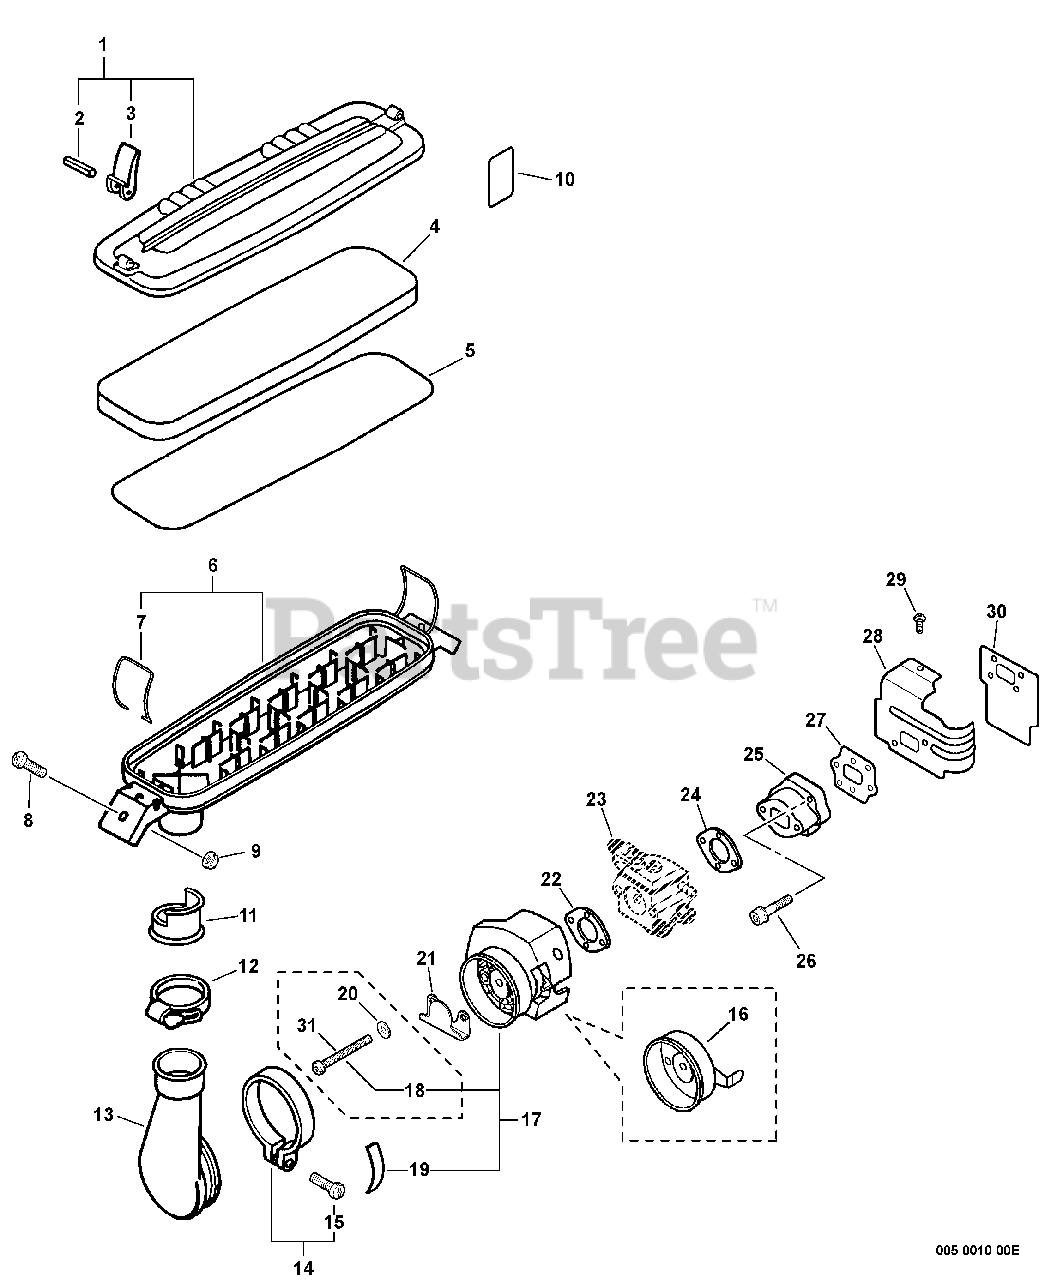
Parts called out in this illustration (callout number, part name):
1	COVER, AIR FILTER
2	PIN, SPRING 3×25
4	FILTER, AIR
5	FILTER, AIR
6	AIR FILTER CASE ASSY
8	SCREW 5×14
9	NUT, FLANGE M5
10	LABEL, CLEANER
11	COLLAR 27
13	ADAPTOR, INTAKE
14	CLAMP KIT
15	SCREW 5×25
17	BRACKET KIT, AIR FILTER
18	SCREW 5×57
19	LABEL, CHOKE
20	WASHER 6.5×13×1
21	PLATE, PREVENT
22	GASKET, INTAKE
23	CARBURETOR
24	GASKET
25	INSULATOR, INTAKE
26	BOLT 5×25
27	GASKET, INTAKE
28	COVER, CYLINDER
29	SCREW 5×10
30	HEAT SHIELD, INTAKE
31	SCREW 5×50
